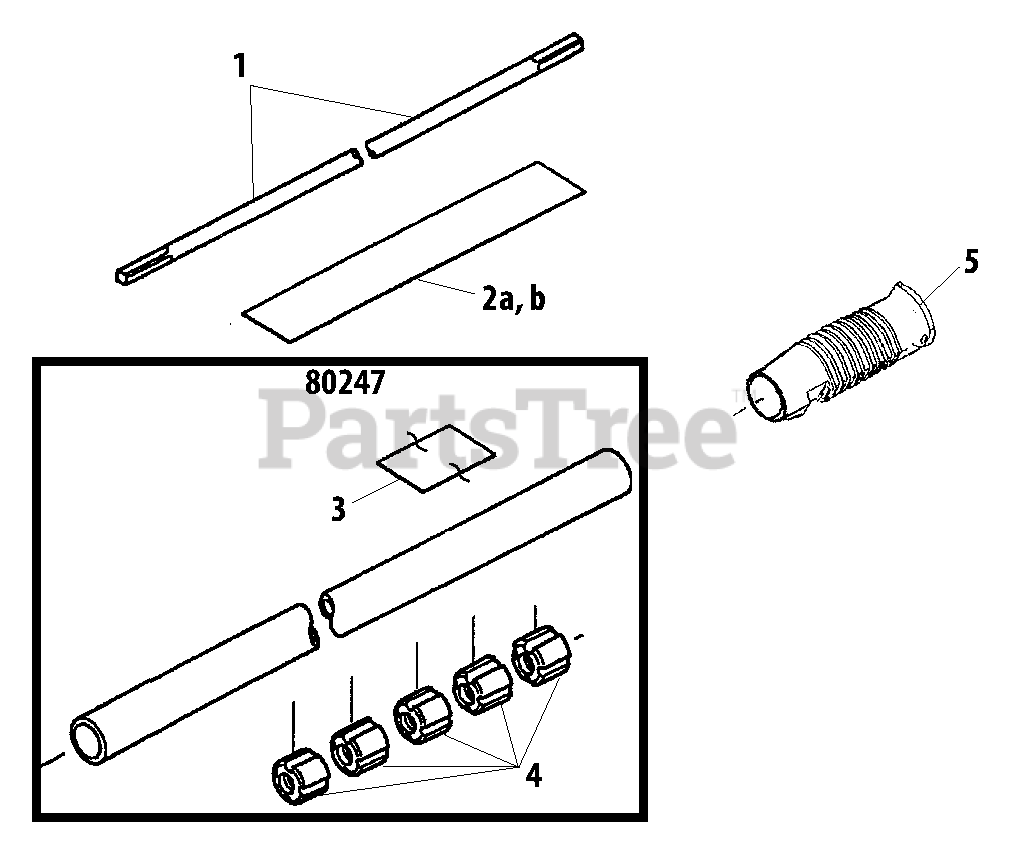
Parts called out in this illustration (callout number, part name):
1	MAINSHAFT
2A	LABEL - MODEL
2B	LABEL - MODEL
3	LABEL, CAUTION
4	BUSHING
5	GRIP, REAR
80247	MAIN PIPE ASSY
